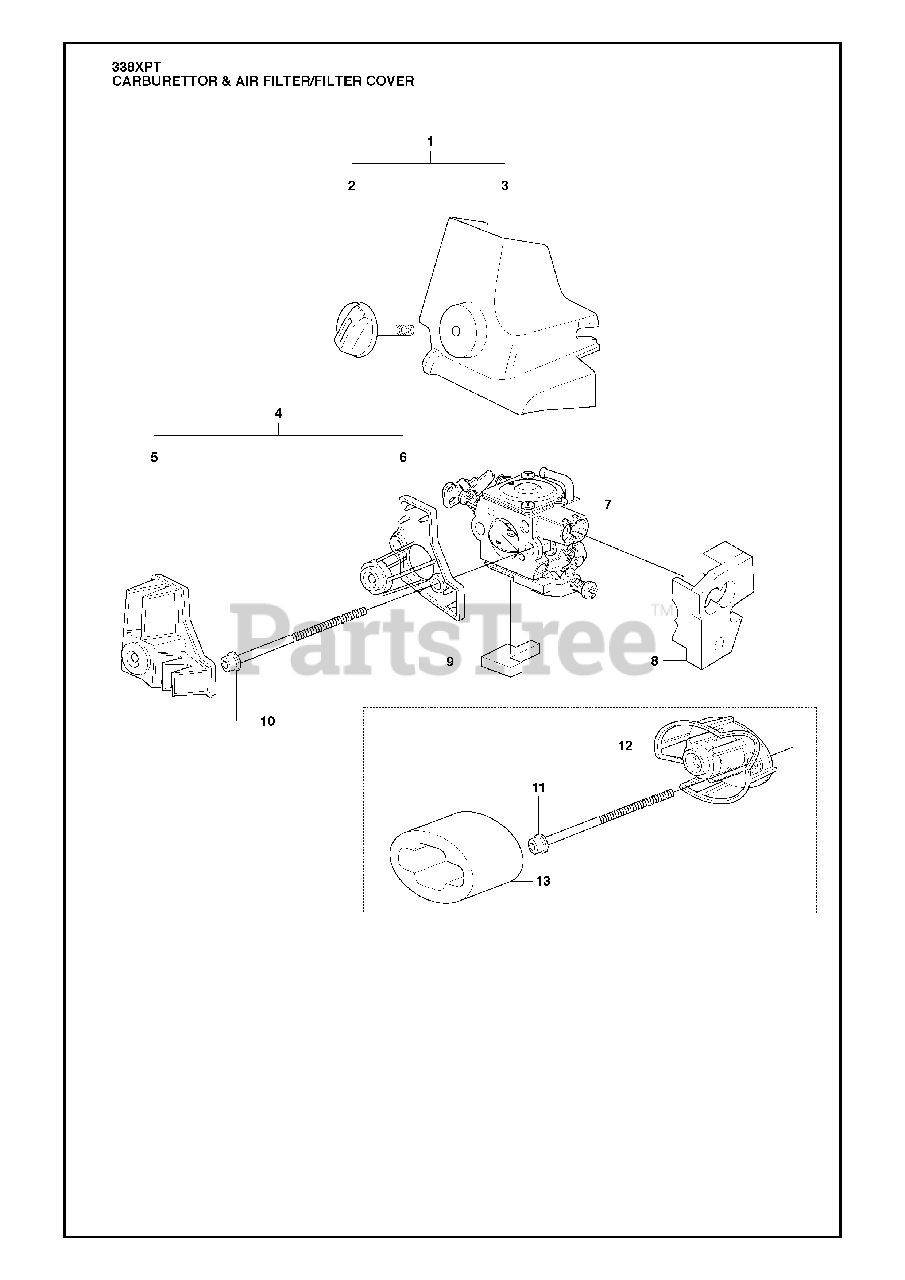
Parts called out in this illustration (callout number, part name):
4	AIR FILTER
4	AIR FILTER KIT
5	AIR FILTER
6	FILTER HOLDER
7	CARBURETOR
11	AIR FILTER
